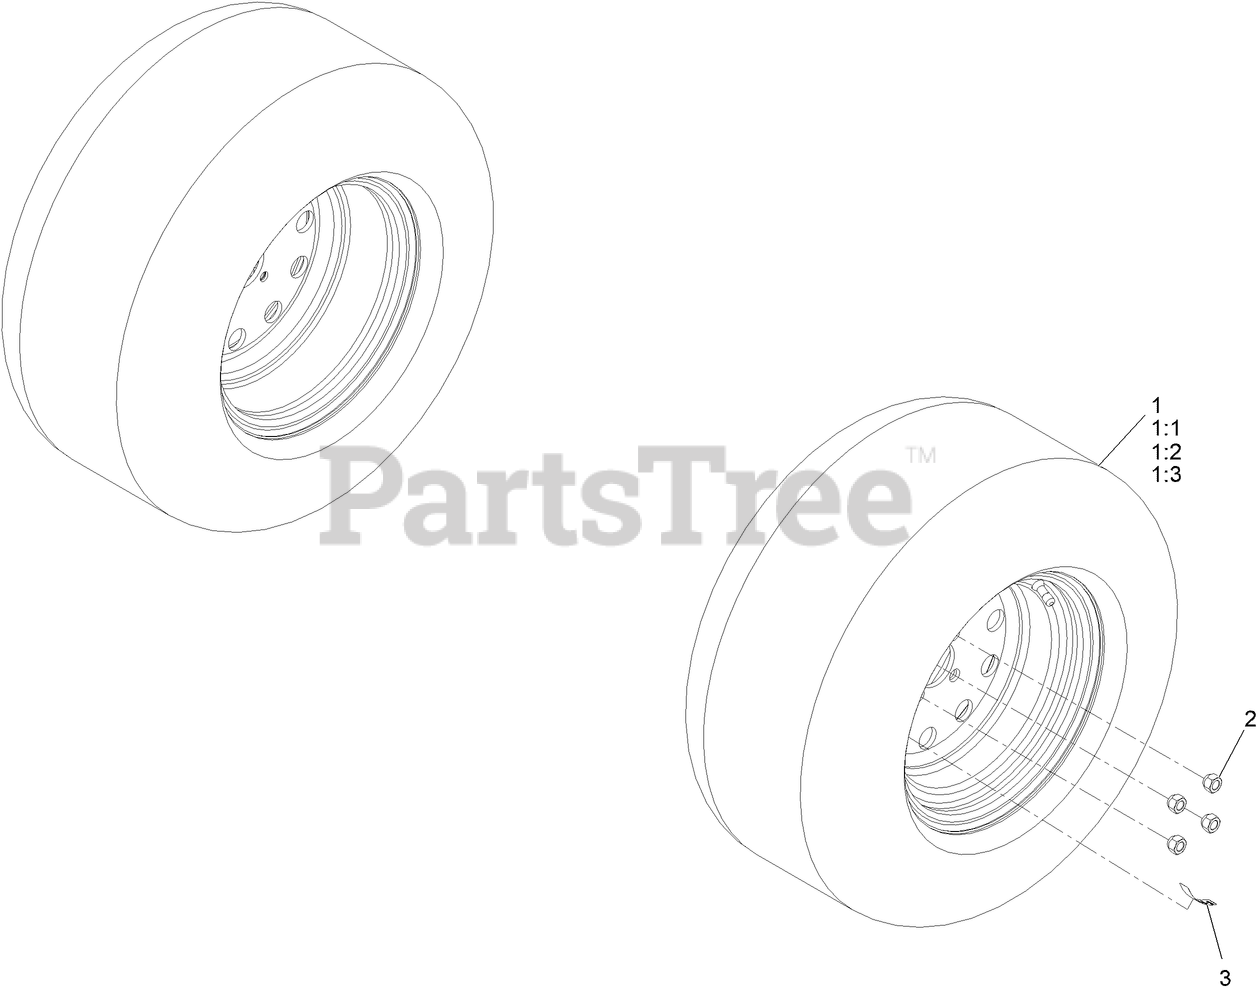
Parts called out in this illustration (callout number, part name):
1	ASM-WHEEL & TIRE
1:2	TIRE-24X12-12
1:3	Stem-Valve
2	NUT-WHEEL
3	DECAL-TORQUE,WHEEL LUG
